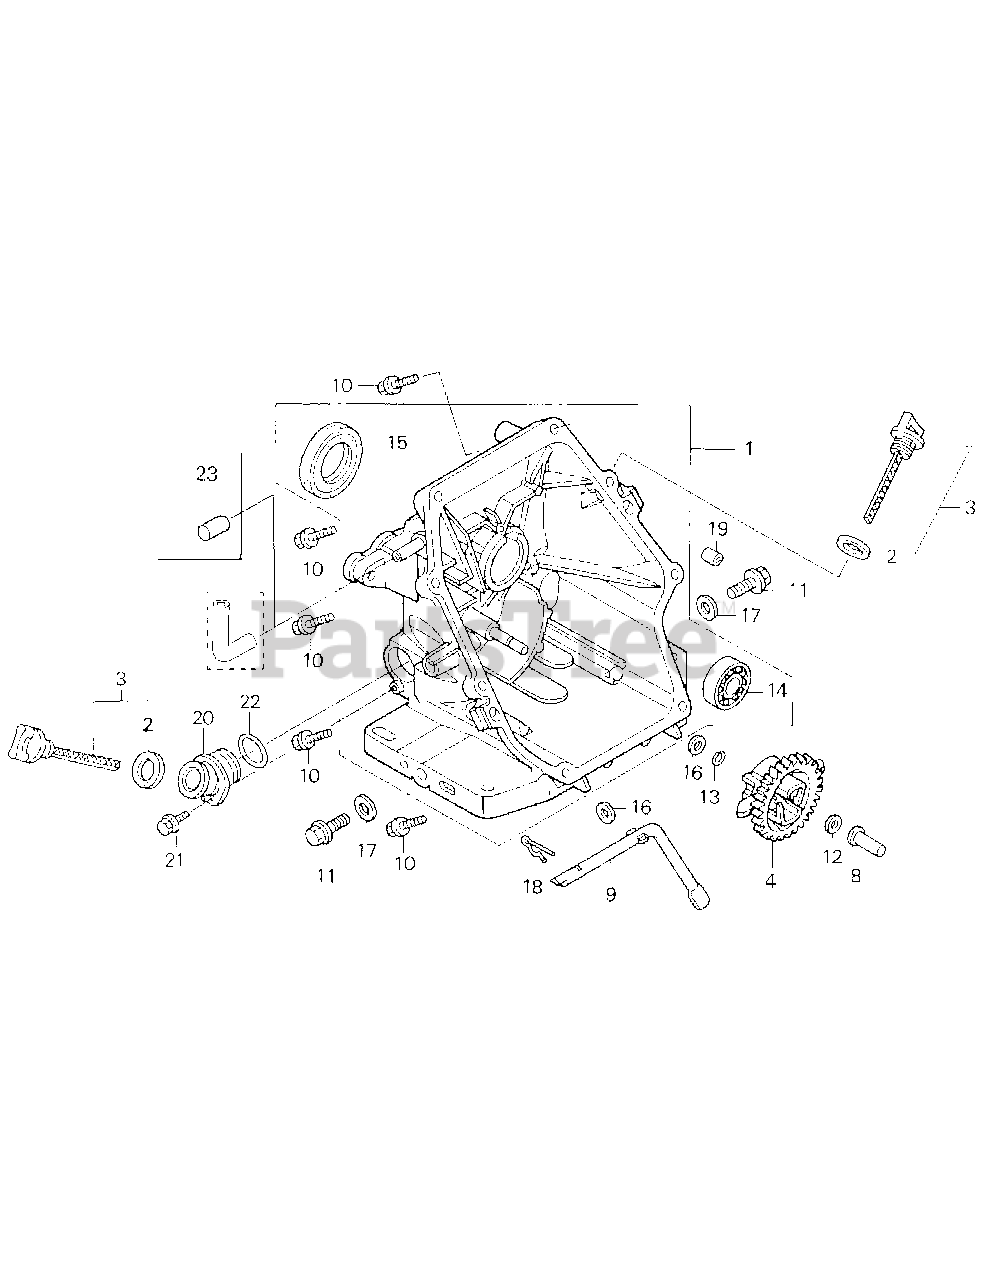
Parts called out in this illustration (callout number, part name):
1	COVER ASSY., CRANKCASE
2	GASKET, OIL FILLER CAP
3	GAUGE ASSY., OIL LEVEL
4	GOVERNOR ASSY.
8	SLIDER, GOVERNOR
9	SHAFT, GOVERNOR ARM
10	BOLT, FLANGE (6X25)
11	BOLT, DRAIN PLUG
12	WASHER, THRUST (6MM)
13	CLIP, GOVERNOR HOLDER
15	OIL SEAL (28X41.25X6)
16	WASHER, PLAIN (6MM)
17	WASHER, DRAIN PLUG (12MM)
18	PIN, LOCK (8MM)
19	PIN, DOWEL (8X20)
